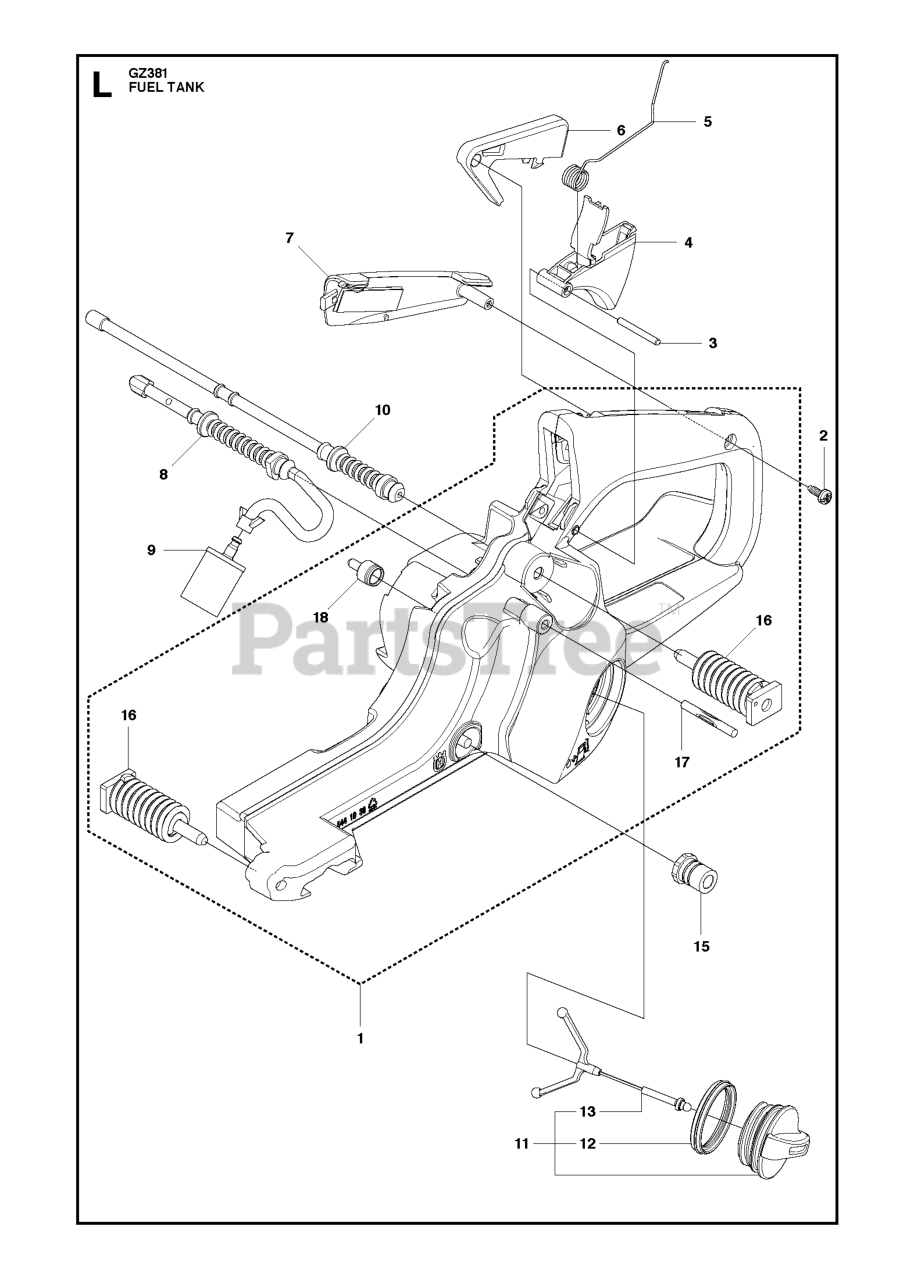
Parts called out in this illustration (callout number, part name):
1	FUEL TANK
2	SCREW CCRPANT
4	THROTTLE CONTROL
6	TRIGGER LOCKOUT BLACK
7	HANDLE INSERT
8	FUEL HOSE
9	FUEL FILTER
10	RP RETURN HOSE
11	TANK CAP ASSY
13	TANK LOCK
15	LATERAL SUPPORT
16	ANTIVIBRATION ELEMENT
17	GROOVED PIN
18	FUEL TANK VENT
